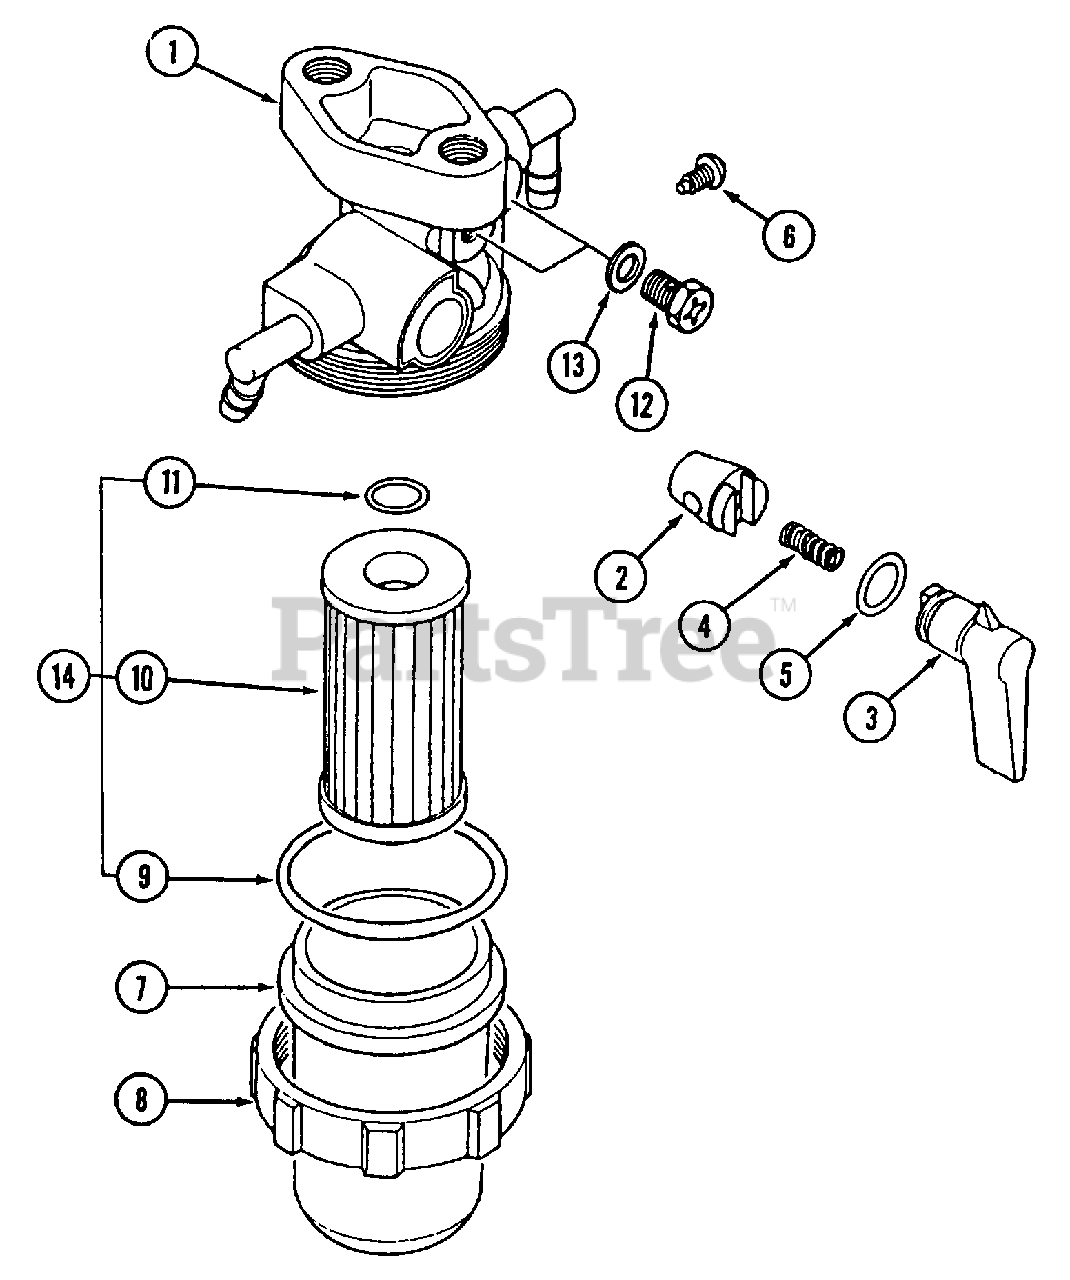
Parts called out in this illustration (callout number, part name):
1	Body Sub Ass'y.
2	Valve
4	Spring Valve
5	O-Ring, Valve
7	Cup, Filter
9	O-Ring, Filter Cup
10	Element
11	O-Ring, Element
12	Screw, Air Vent
14	Service Kit, Fuel Filter
